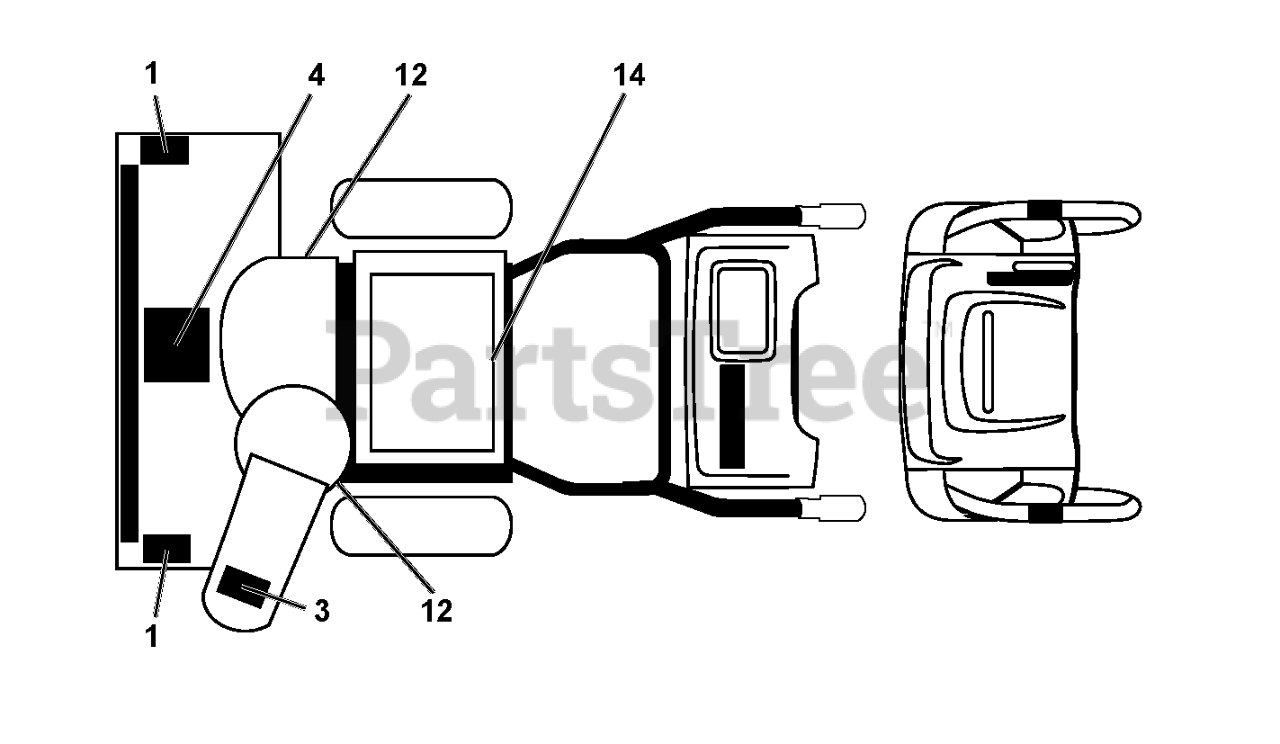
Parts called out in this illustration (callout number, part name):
1	DECAL.AUGER.SAFETY.
3	DECAL.CHUTE.SAFETY.
4	DECAL.AUGER."
12	DECAL.BELT.GUARD.
14	DECAL.FENDER
